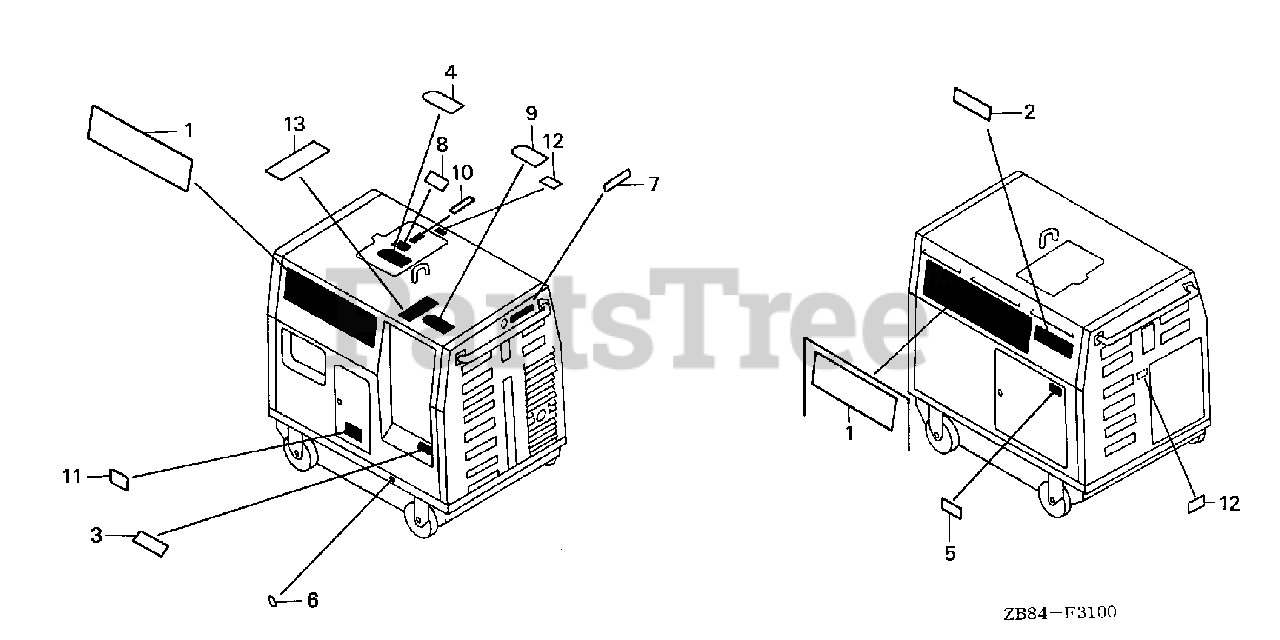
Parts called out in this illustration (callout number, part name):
1	MARK, EMBLEM (EX4500)
1	EMBLEM (EX4500)
2	PLATE, CAUTION
2	LABEL, SPECIFICATION
3	LABEL, RAIN WARNING (ENGLISH)
4	MARK, CAUTION (ENGLISH/FRENCH/SPANISH)
5	MARK, AIR CLEANER
6	MARK, GROUND
7	MARK, EX. CAUTION
8	MARK, CAUTION (ENGLISH/FRENCH/SPANISH)
9	LABEL, CONNECT WARNING (ENGLISH)
10	PLATE, FUEL INDICATION
11	MARK, OIL CAUTION
12	LABEL, FUEL CAUTION
13	LABEL, OPERATOR WARNING
